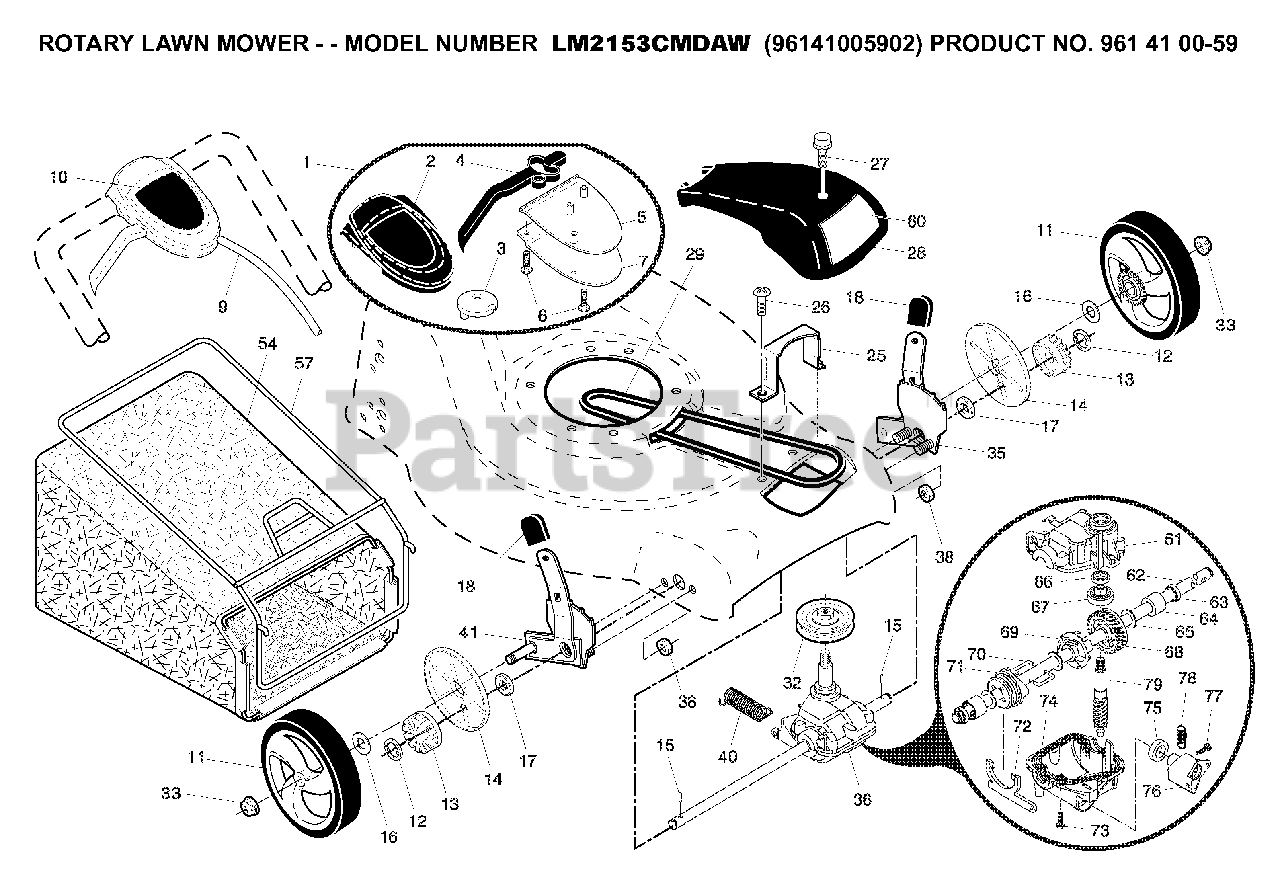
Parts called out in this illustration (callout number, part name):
3	PULLEY, DRIVE CONTROL
6	SCREW, PHILLIPS HEAD 10 X 5/8
7	BRACKET.DRIVE.CONTROL.MOUNT
9	CABLE.ASM.
12	E-RING 7/16 RE
13	PINION.14.TEETH.FGD
14	COVER.DUST.WHEEL
15	PAWL, DRIVE
16	WASHER FLUT
17	BEARING
18	SELECTOR KNOB
25	KEEPER.BELT.21.EZ.FWGD
26	SELF-TAPPING SCREW 5/16-18X3/4
27	SCREW, HEX HD TAPPING #10-24 1
29	BELT.DRIVE.FGD.
32	RP PULLEY.DRIVE.EZ
33	NUT.HEX.FLANGE.3/8-16.LOCKNUT
35	WHEEL ADJ KIT LH
36	TRANSMISSION.21RD
38	LOCKNUT
40	SPRING RETURN
41	WHEEL ADJ KIT RH
54	GBAG.34710010.BLACK.GE
57	FRAME, GRASSBAG
61	GEARCASE.HOUSING
62	SHAFT.OUTPUT
63	SEAL.OUTPUT.SHAFT
66	SEAL INPUT SHAFT
68	GEAR.27.TEETH.WALK.MOWER
70	WIRE, FORMED
74	GEARCASE.HOUSING
77	SCREW.LEVER.
79	SHAFT, INPUT
